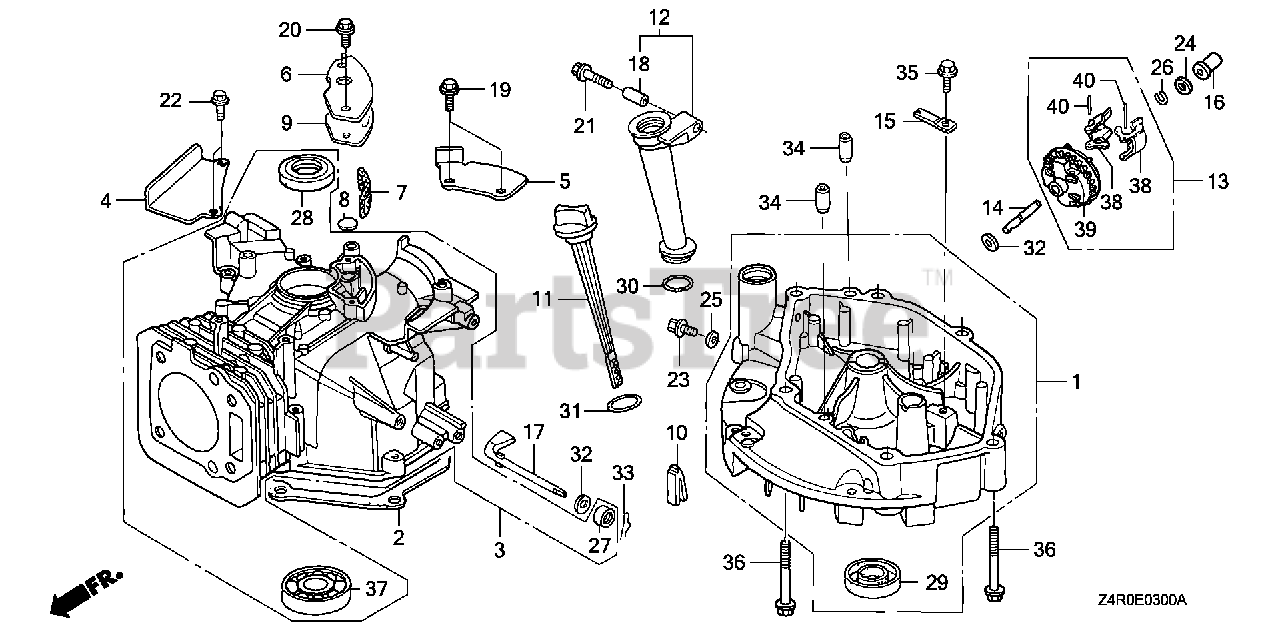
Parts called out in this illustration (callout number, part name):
1	PAN ASSY., OIL
2	GASKET, OIL PAN
3	CYLINDER ASSY.
4	PLATE, GUIDE
5	PLATE A, GUIDE
6	COVER, BREATHER
7	FILTER, BREATHER
8	VALVE, BREATHER
9	GASKET, BREATHER COVER
10	RUBBER, OIL RETURN
11	GAUGE, OIL LEVEL
12	EXTENSION, OIL FILLER
13	GOVERNOR ASSY.
14	SHAFT, GOVERNOR HOLDER
15	PLATE, GOVERNOR SHAFT HOLDER
16	SLIDER, GOVERNOR
17	SHAFT, GOVERNOR ARM
18	COLLAR, EXTENSION
19	BOLT, FLANGE (6X12) (CT200)
20	BOLT, FLANGE (6X14) (CT200)
21	BOLT, FLANGE (6X32)
22	BOLT, FLANGE (6X20) (CT200)
23	BOLT, DRAIN PLUG
24	WASHER, THRUST (6MM)
25	WASHER, DRAIN PLUG (10.2MM)
26	CLIP, GOVERNOR HOLDER
27	OIL SEAL (6X11X4) (ARAI)
28	OIL SEAL (25X38X7) (ARAI)
29	OIL SEAL (25.4X40X7)
30	O-RING (22.1X2.2)
31	O-RING (26X2.7)
32	WASHER, PLAIN (6MM)
33	PIN, LOCK (8MM)
34	PIN, DOWEL (8X14)
35	BOLT, FLANGE (6X12)
36	BOLT, FLANGE (8X50)
37	BEARING, RADIAL BALL (6205)
38	WEIGHT, GOVERNOR
39	HOLDER, GOVERNOR WEIGHT
40	PIN, GOVERNOR WEIGHT
